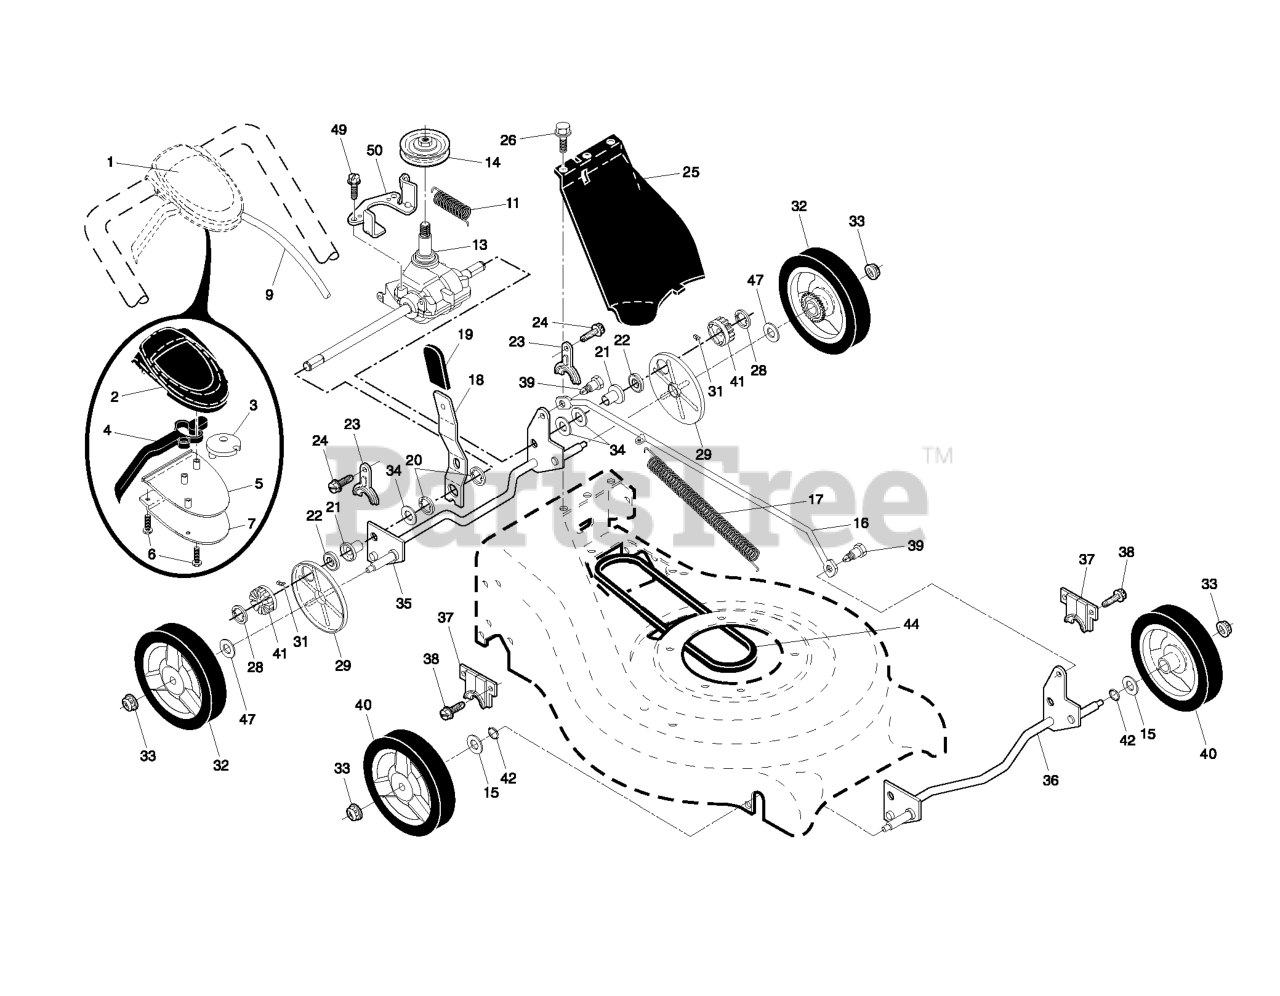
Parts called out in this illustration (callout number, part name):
1	CONTROL.DR.AW.21FGD.
2	COVER TOP AUTO WALK CONTROL
3	PULLEY.CAM.DRIVE.CONTROL.EZ
4	LEVER.BLACK
5	COVER BOTTOM AUTO WLK CONTROL
6	SCREW, PHILLIPS HEAD 10 X 5/8
7	BRACKET.DRIVE.CONTROL.MOUNT.BL
9	CABLE.ASSY.RGD.EZ.AUTO
13	TRANSMISSION.21.RWGD
14	PULLEY.1.PIECE
15	WASHER.FLAT.1/2
16	ROD.CONNECTING.SPT.BLACK
17	SPRING EXTENSION
18	SPRING.SELECTOR.
19	KNOB, SELECTOR SPRING
21	BEARING SUPPORT
22	BEARING
23	BRACKET
24	SCREW 14-20 X 5/8
25	COVER.DRIVE.21.RWGD.MO
28	E-RING 7/16 RE
29	COVER.DUST.WHEEL
31	PAWL, DRIVE
32	WHEEL & TIRE ASSY, REAR
33	NUT.HEX.FLANGE.3/8-16.LO(3 2)
35	SHAFT ASSY REAR
36	SHAFT ASSY, FRONT
37	RETAINER.FRONT.SHAFT
39	SHOULDER BOLT SEMI GIMLET PT.
40	WHEEL & TIRES ASSY, FRONT
41	PINIION.14.TOOTH.RGD
42	O-RING..070X.487.NEOPRENE
44	BELT.RGD.VS
47	WASHER FLUT
50	BELT KEEPER
